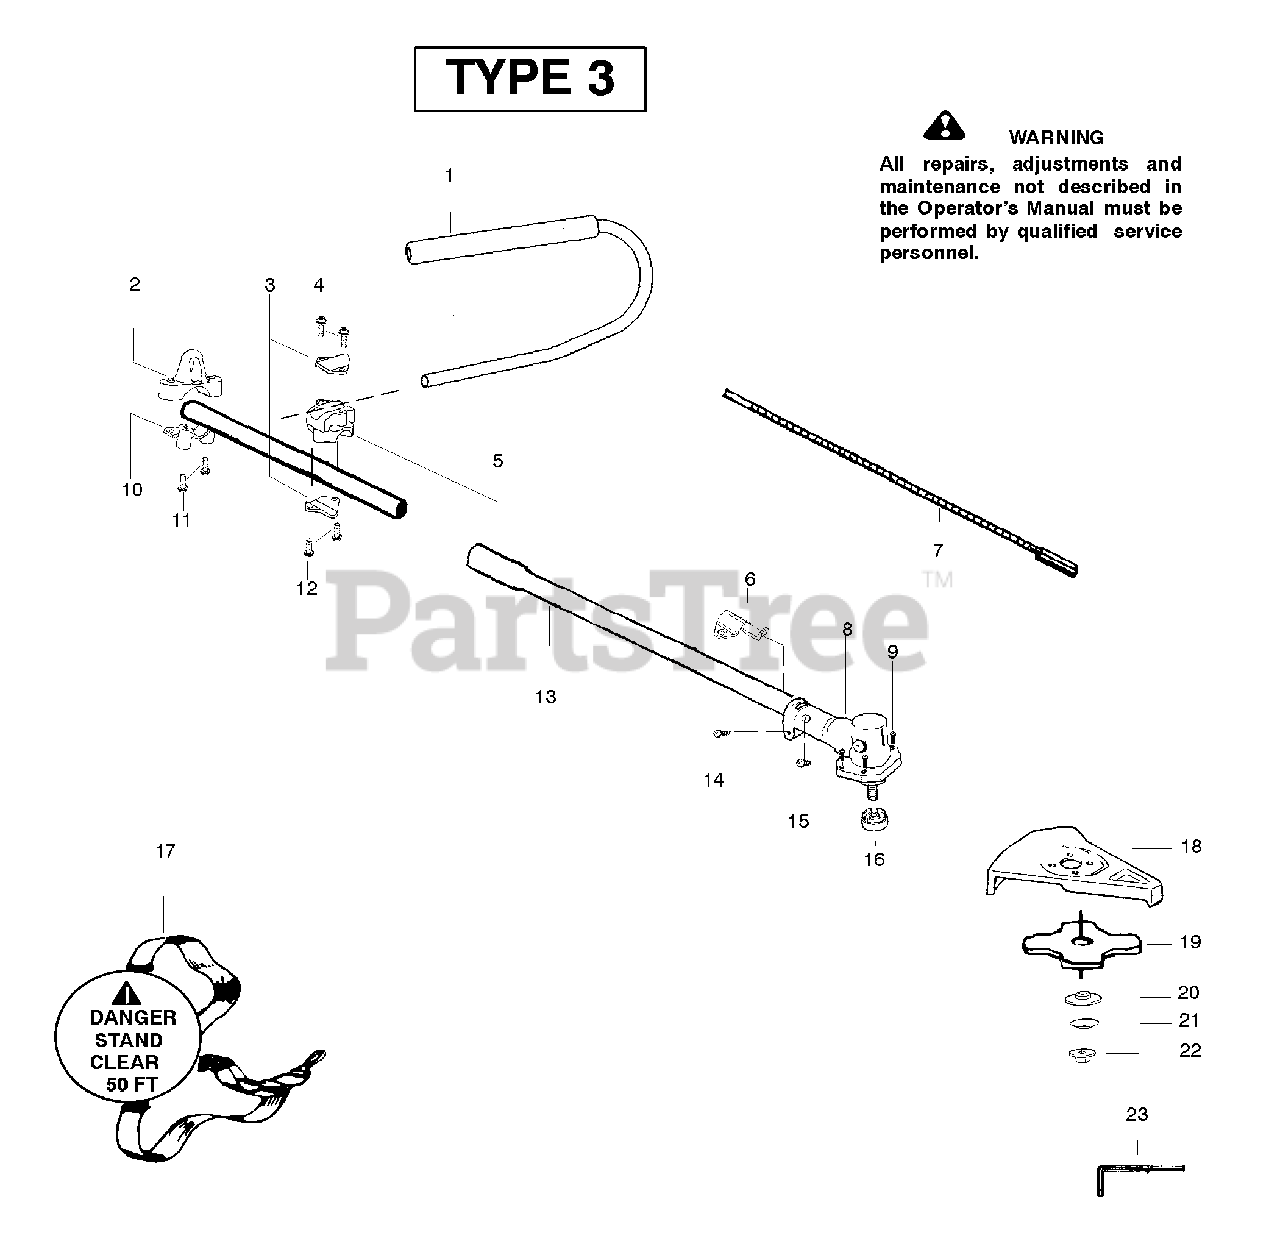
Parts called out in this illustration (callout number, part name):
1	Kit-Handlebar
2	Clamp-Harness Upper
3	Clamp-Bracket
5	Clamp-Handlebar (7/8")
5	Clamp-Handlebar (1")
6	Bracket-Shield
7	Flexshaft-Split boom
8	Assy-Gearbox
10	Clamp-Harness Lower
13	Assy.-Driveshaft
15	Screw-Alignment
16	Dust cup - Blade
17	Assy-Shoulder Strap
18	Kit-Blade Shield
19	Accy.-Weed Blade (8")
20	Washer-Blade Retaining
21	Washer-Belleville
22	Nut-Flange
23	Wrench-Hex (5/32")
